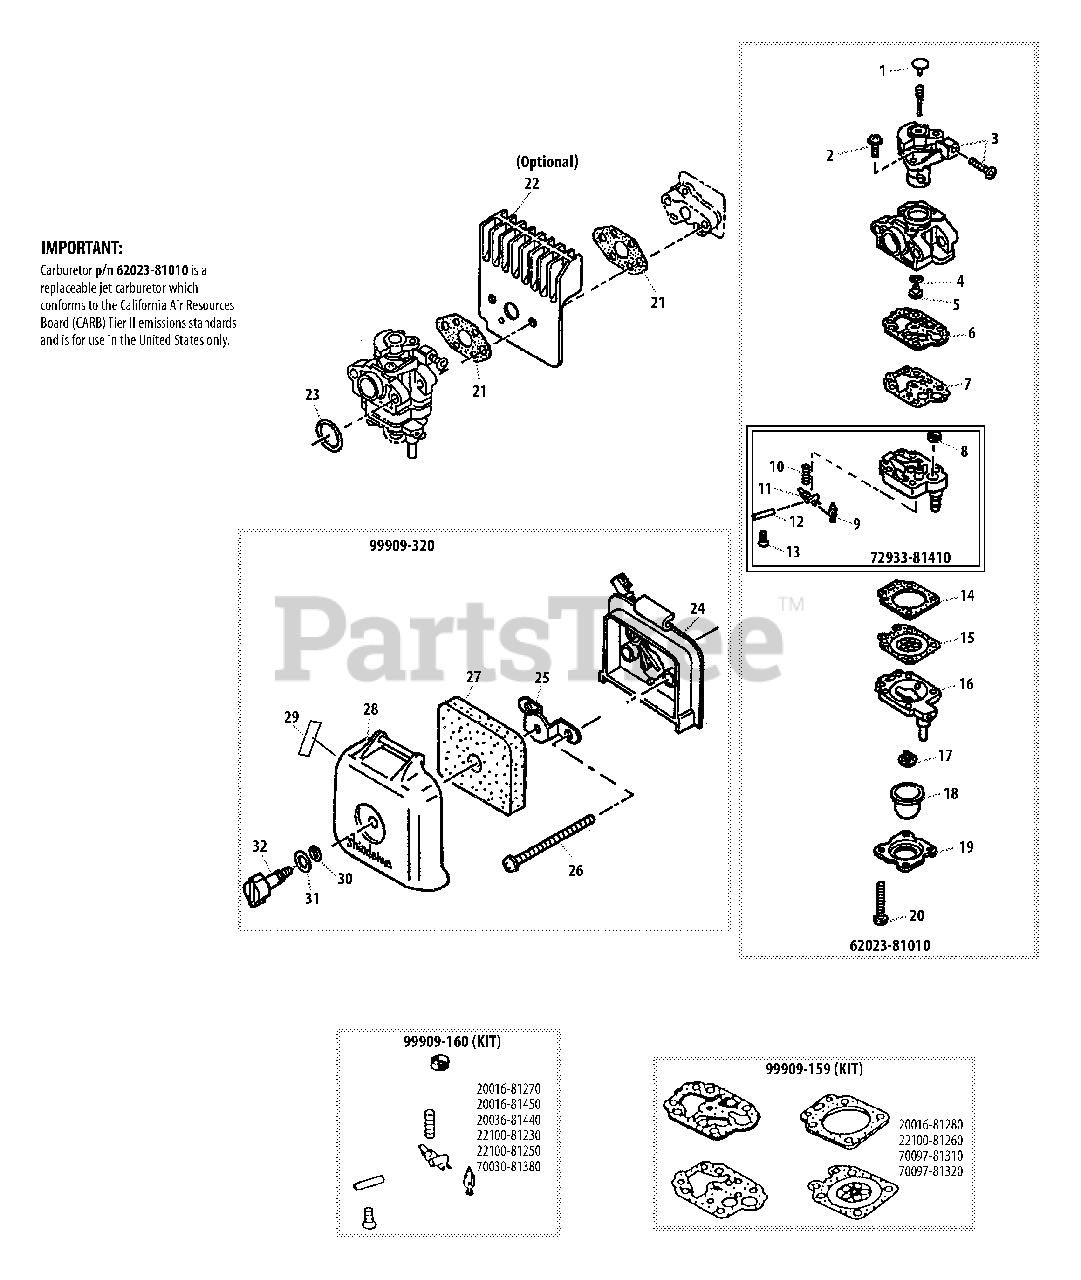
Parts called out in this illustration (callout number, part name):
1	PLUG, WELCH
2	SCREW
3	THROTTLE VALVE ASSY
4	O-RING
5	JET, MAIN
6	GASKET, PUMP
7	DIAPHRAGM, PUMP
8	STRAINER
9	VALVE, INLET NEEDLE
10	SPRING, METERING LEVER
11	LEVER, METERING
12	PIN, METERING LEVER
13	SCREW, METERING LEVER PIN
14	GASKET, METERING
15	DIAPHRAGM, METERING
16	BASE, PURGE
17	VALVE, CHECK
18	BULB, PURGE
19	RETAINER, PURGE BULB
20	SCREW, PUMP COVER
21	GASKET
22	DEFLECTOR, HEAT
23	O-RING - 15
24	CASE, AIR FILTER
25	PLATE, PREVENT
26	SCREW - 5X67
27	FILTER, AIR - FOAM
28	COVER, AIR FILTER
29	LABEL - CHOKE
30	O-RING
31	WASHER - CONICAL
32	THUMBSCREW
62023-81010	CARBURETOR
72933-81410	BASE, PURGE
99909-159	DIAPHRAGM/GASKET KIT
99909-160	REPAIR KIT
99909-320	AIR FILTER ASSY
